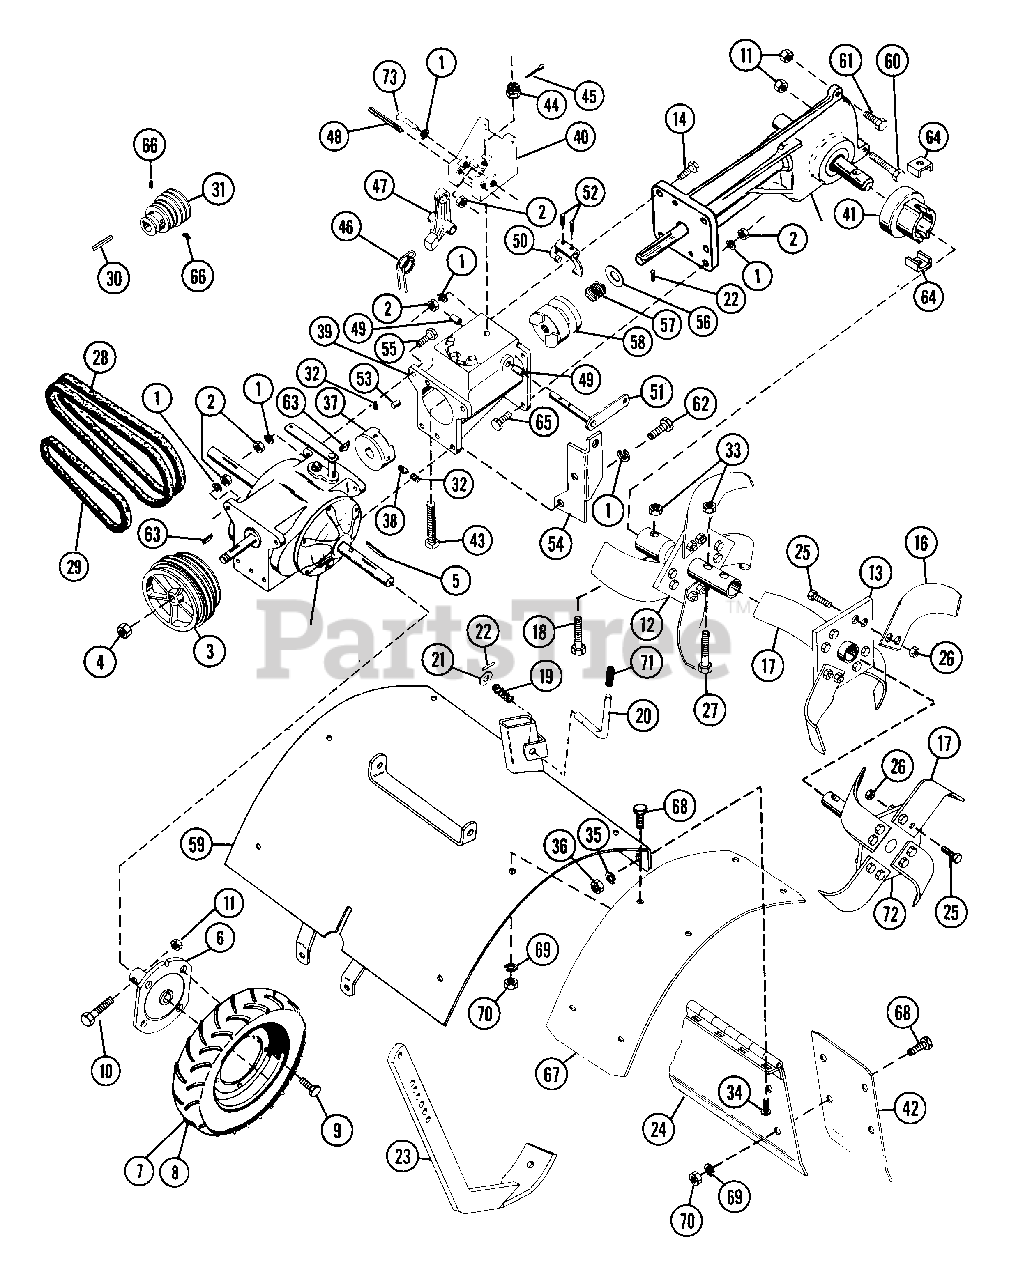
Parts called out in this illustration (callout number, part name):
1	WSHR-LK .375X.115 HVY PL
2	NUT-HEX .375-16
3	DRIVE SHEAVE
4	NUT-LK-CTR .75-16 PL
5	KEY-FTHR .25X1.875X.25 SAE
6	WHEEL HUB
7	R H TIRE AND RIM ASSY
8	L H TIRE AND RIM ASSY
9	SCR-TAP .500-20X.62 HH PL
10	BLT-HEX .31-18X2.00 PL GR2
11	NUT-LK .312-18 GR A PL
12	INNER TINE HUB
13	OUTER TINE HUB
14	BLT-HEX .38-16X1.75 PL GR2
15	NUT-LK .375-16 PL
16	R KNIFE TINE
17	L KNIFE TINE
18	BLT-HEX .38-16X2.75 GR8
19	SG-COMP .045X.50X1.187
20	DEPTH REGULATING PIN
21	WSHR-FL-STL .38X.875X.083 PL
22	PIN-ROLL .125X1.00
23	DEPTH SHOE
24	TAILBOARD
25	BLT-HEX .44-14X1.00 GR5
26	NUT-LK-TOP .437-14 GR C PL
27	BLT-HEX .38-16X2.00 GR8
28	V-BELT, SAE 380-RAW EDGE (SET)
29	V-BELT, SAE 380-RAW EDGE (SET)
30	KEY-SQ .25 X 1.25 X .25 SAE
31	ENGINE SHEAVE
32	SCR-SET .32-18X.38 SKHCUPNL OH
33	NUT-LK TOP .375-16 GR C YWZC
34	BLT-RDHDSQSHNK .31-18X.50 YZ
35	WSHR-LK .313X.093 MED HICLR
36	NUT-HEX .312-18
37	TILLER DRIVING JAW
38	SCR-SET .32-18X.50 SKHHOP OH
39	CLUTCH HOUSING
40	HANDLEBAR BRACKET
41	DUST CAP
42	TAILBOARD EXTENSION
43	SWIVEL BOLT
44	NUT-SL .50-13
45	PIN-COTR .12X1.0 PL
46	SG-TORS .109X.88X2.25
48	PIN-ROLL .313X2.00
49	BSHG-SLV .500X.687X.500
50	CLUTCH FORK
51	TINE ENGAGING FORK SHAFT
52	PIN-ROLL .188X1.00
53	DOWEL PIN
54	ENGAGEMENT PIVOT BRACKET
55	BLT-HEX .38-16X1.50 PL GR2
56	WSHR-FL-STL .755X1.375X.125
57	SG-COMP .080X.97X2.18 WLD14
58	TILLER JAW CLUTCH
59	TINE HOOD WITH DECALS
60	BLT-HEX .31-18X3.50 PL GR2
61	BLT-HEX .31-18X1.25 PL GR2
62	BLT-HEX .38-16X1.75 PL GR2
63	KEY-FTHR .188X1.25X.187 SAE
65	BLT-HEX .38-16X2.00 PL GR2
66	SCR-SET .32-18X.38 SKHCUPNL OH
67	TINE HOOD EXTENSION
68	BLT-HEX .25-20X.50 PL GR2
69	WSHR-LK .250X.077 HVY PL
70	NUT-HEX .250-20 PL
72	OUTER TINE HUB
73	BLT-HEX .38-16X1.00 PL
